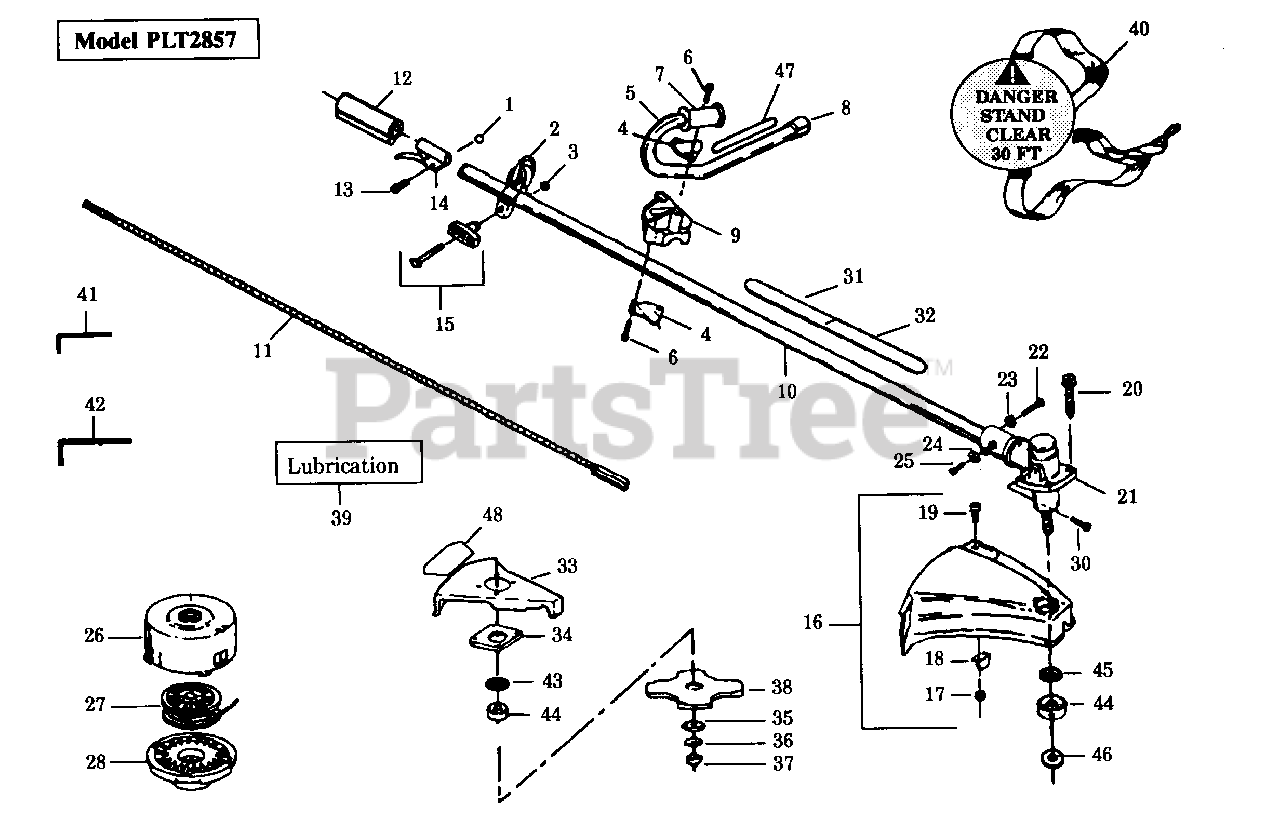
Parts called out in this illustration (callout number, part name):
2	Clamp Harness Ass'y.
4	Handlebar Bracket
5	Handlebar
7	Handlebar Grip
8	Handlebar Cap
9	Handlebar Clamp
10	Drive Shaft Housing
11	Drive Shaft
12	Drive Shaft Grip
14	Throttle Lever Ass'y.
15	"T" Handle Kit
16	Shield Kit Ass'y.
17	Locknut
18	Line Limiter
20	Screw, Use w/ plastic shield
20	Screw, Use w/ metal shield
21	Gear Box Ass'y.
23	Lockwasher
24	Lockwasher
26	Hub Ass'y.
27	Spool w/Line
31	Shaft Warning Decal-Upper
32	Shaft Warning Decal-Lower
33	Shield
34	Shield Retention Plate
36	Washer
38	Weed Blade
39	Shaft Lubrication
40	Shoulder Strap
41	Hex Wrench (5/32)
42	Hex Wrench (3/16)
44	Dust Cup
46	Grass Washer
47	Handlebar Decal
48	Blade Direction Decal (Not a serviceable part)
